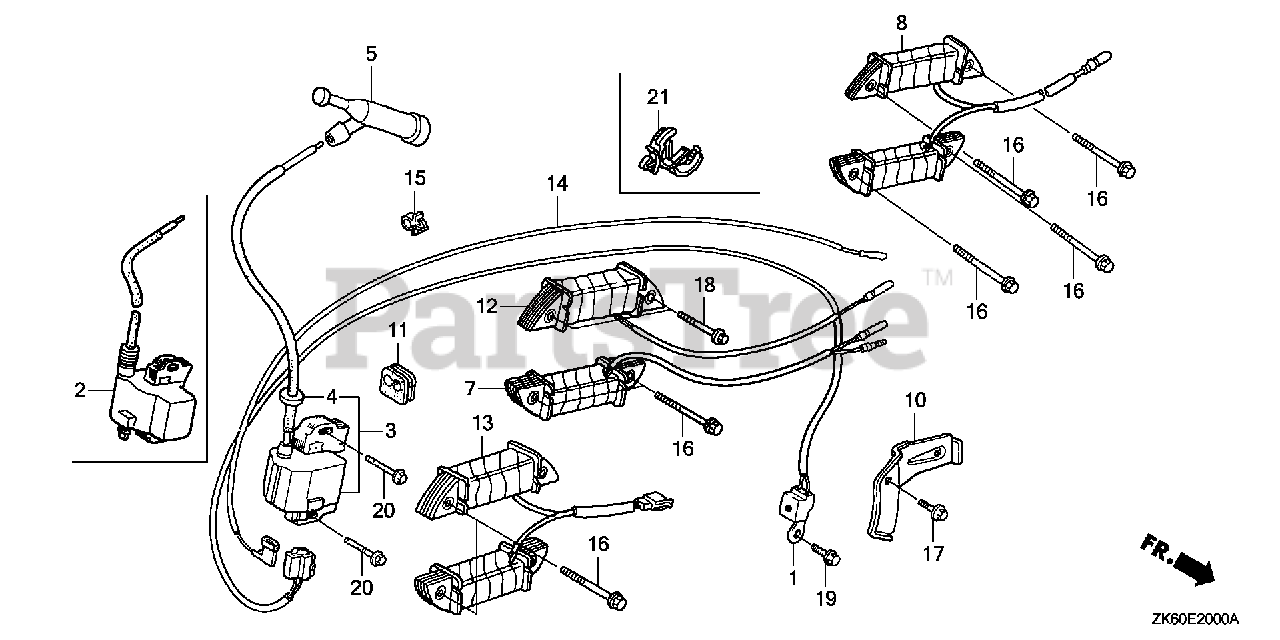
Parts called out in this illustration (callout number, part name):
2	COIL ASSY., IGNITION
5	CAP ASSY., NOISE SUPPRESSOR (NICHIWA Y-EZ RTFM256)
11	GROMMET, WIRE
14	WIRE, STOP SWITCH (430MM)
20	BOLT, FLANGE (6X28) (CT200)
